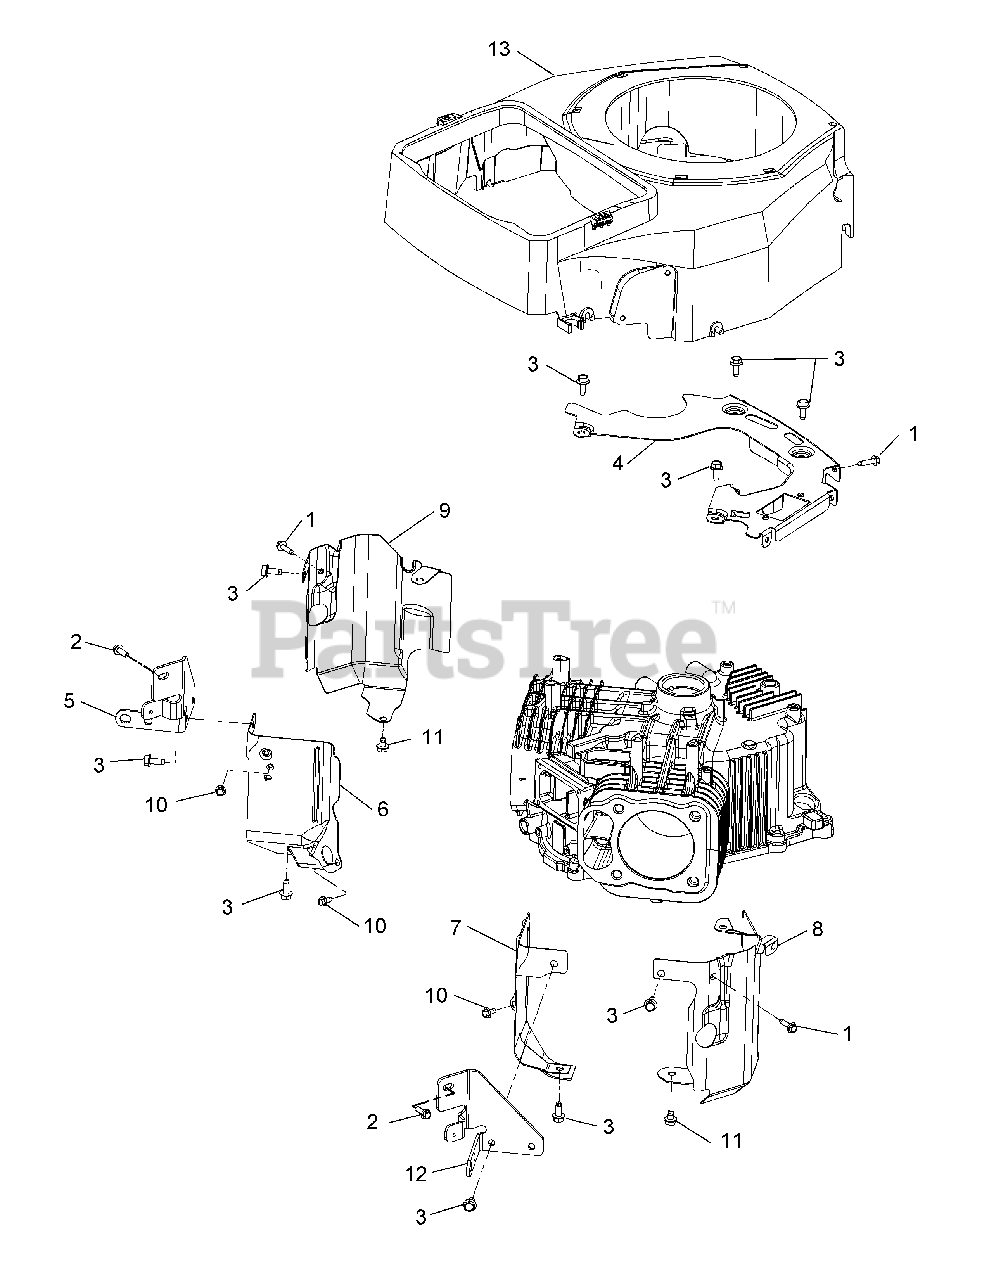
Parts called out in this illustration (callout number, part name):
1	Thread Forming Screw
3	Thread Forming Screw
4	Backing Plate
5	Air Cleaner Base Bracket (#1)
6	Valley Baffle, #1 Cylinder
7	Valley Baffle, #2 Cylinder
8	Left Barrel Baffle
9	Right Barrel Baffle
10	Thread Forming Screw
11	Thread Forming Screw
12	Air Cleaner Base Bracket (#2)
13	Blower Housing Kit
